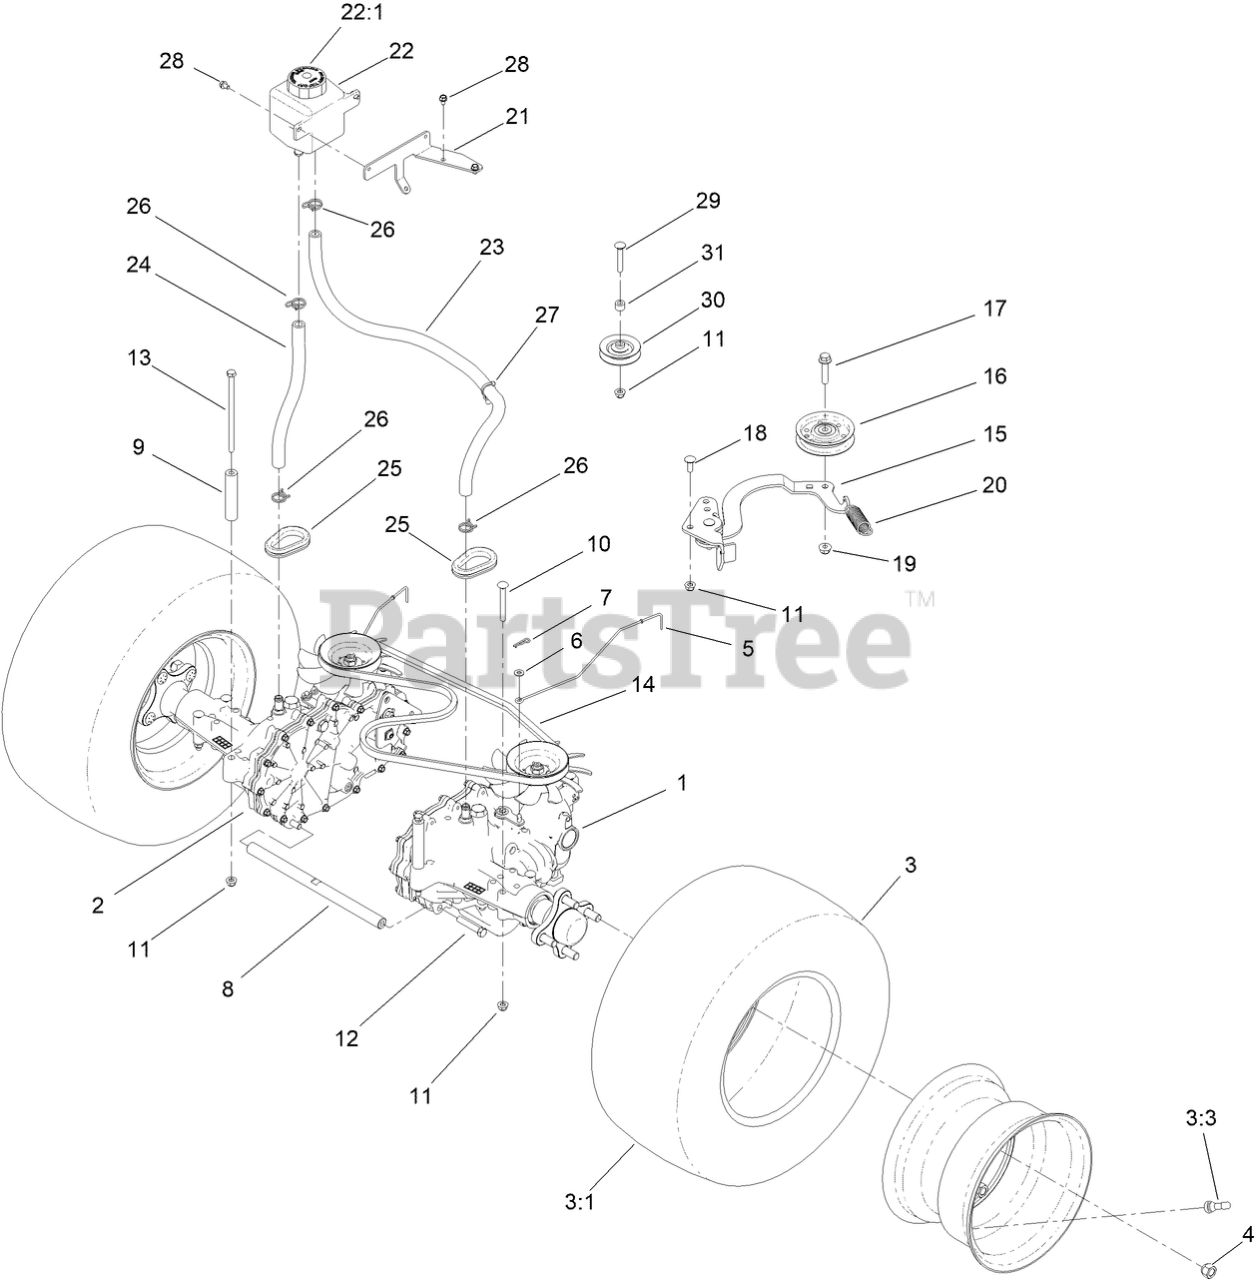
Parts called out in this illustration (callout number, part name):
1	TRANSMISSION, ZT-3100 LH
2	TRANSMISSION, ZT-3100 RH
3	TIRE ASM
4	NUT-LUG
5	ROD-BYPASS
6	WASHER-FLAT
7	PIN-COTTER
8	SHAFT-CROSS, HYDRO
9	SPACER - TRANSMISSION
10	SCREW-CARR
11	NUT-HF, NI
12	SCREW-HH W/LOCTITE
13	SCREW-HH
14	BELT-V
15	IDLER ARM ASM
16	PULLEY-IDLER, FLAT
17	SCREW-HHF
18	BOLT-CARR
19	NUT-HF, NI
20	SPRING-EXTENSION
21	BRACKET - EXPANSION TANK
22	TANK-HYD
22:1	CAP-RESERVOIR, HYD
23	HOSE-HYDRO
24	HOSE-OVERFLOW
25	GROMMET
26	CLAMP-HOSE
27	CLIP-TIE
28	SCREW-HWH
29	BOLT-CARR
30	PULLEY-IDLER
31	SPACER
